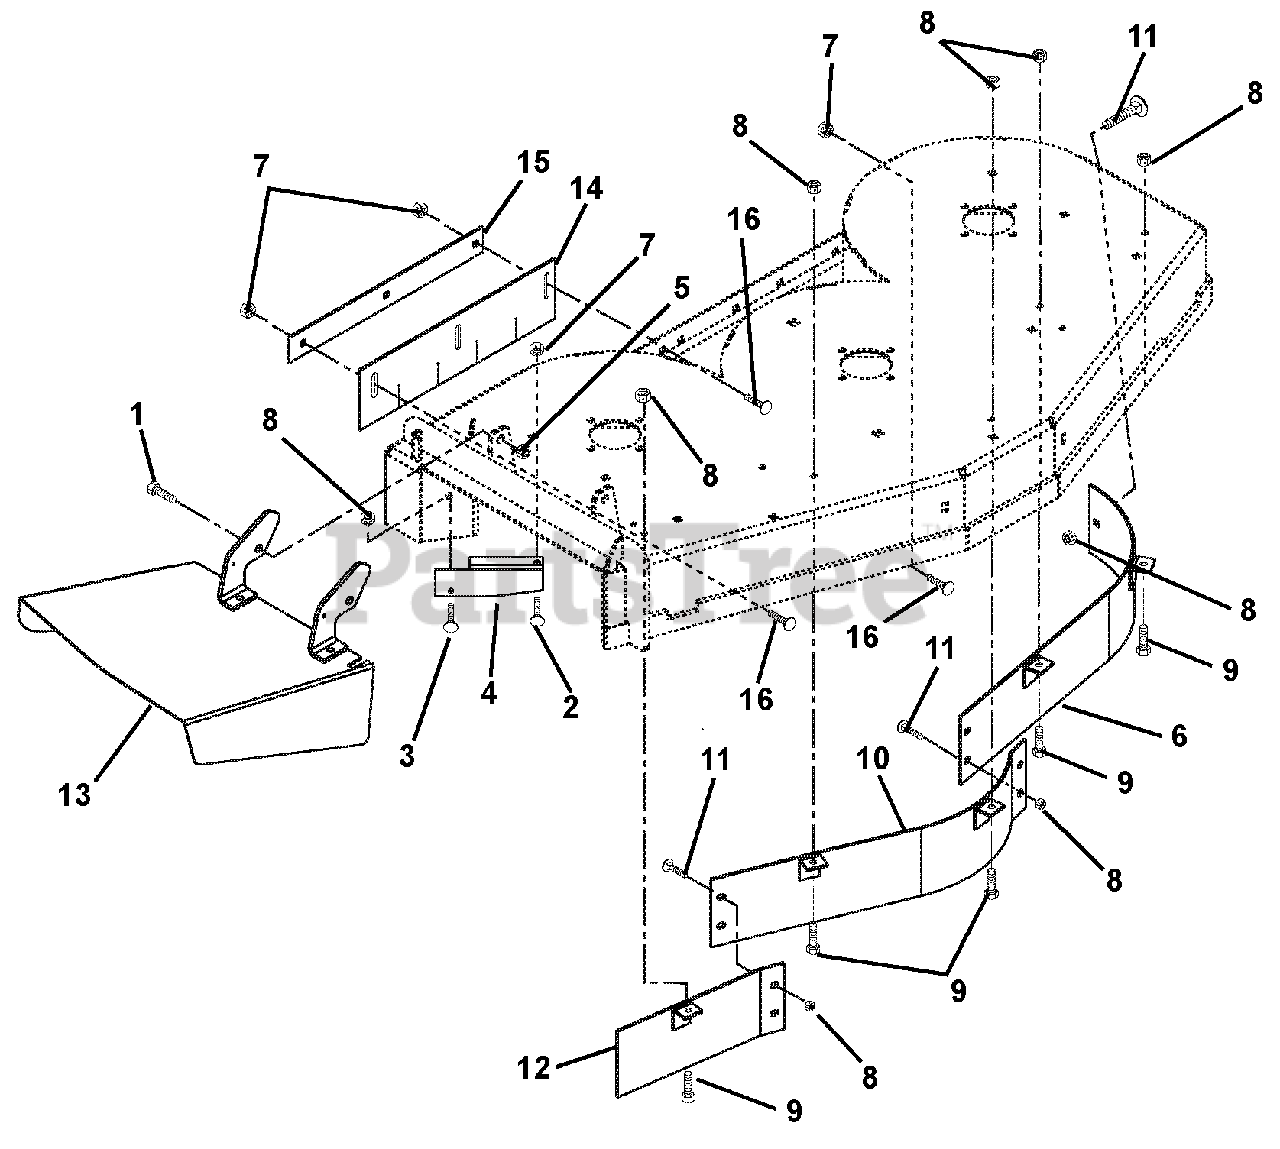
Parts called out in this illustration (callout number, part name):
1	Bolt-Hex .50-13 x 1.25 Grade 5
2	Bolt-Round Head Square Neck .38-16 x .75 Grade 5
3	Bolt-Round Head Square Neck .31-18 x 1.00 Grade 5
4	Deflector /48" (106, 108, 116)
5	Nut-Locking-Nylon .50-13
6	Weldment- Upper Baffle Left (106, 108, 116)
7	Nut-Locking-Top-Flange .38-16
8	Nut-Locking-Top-Flange .31-18
9	Bolt-Hex .31-18 x .75 Grade 5
10	Weldment- Upper Baffle Center (106, 108, 116)
11	Bolt-Round Head Square Neck .31-18 x .75 Grade 5
12	Weldment, Right Hand Baffle-Upper (106, 108, 116)
13	Chute-Discharge
14	Skirt- Rubber
15	Strip- Striper Mount
16	Bolt-Round Head Square Neck .38-16 x 1.00 Grade 5
